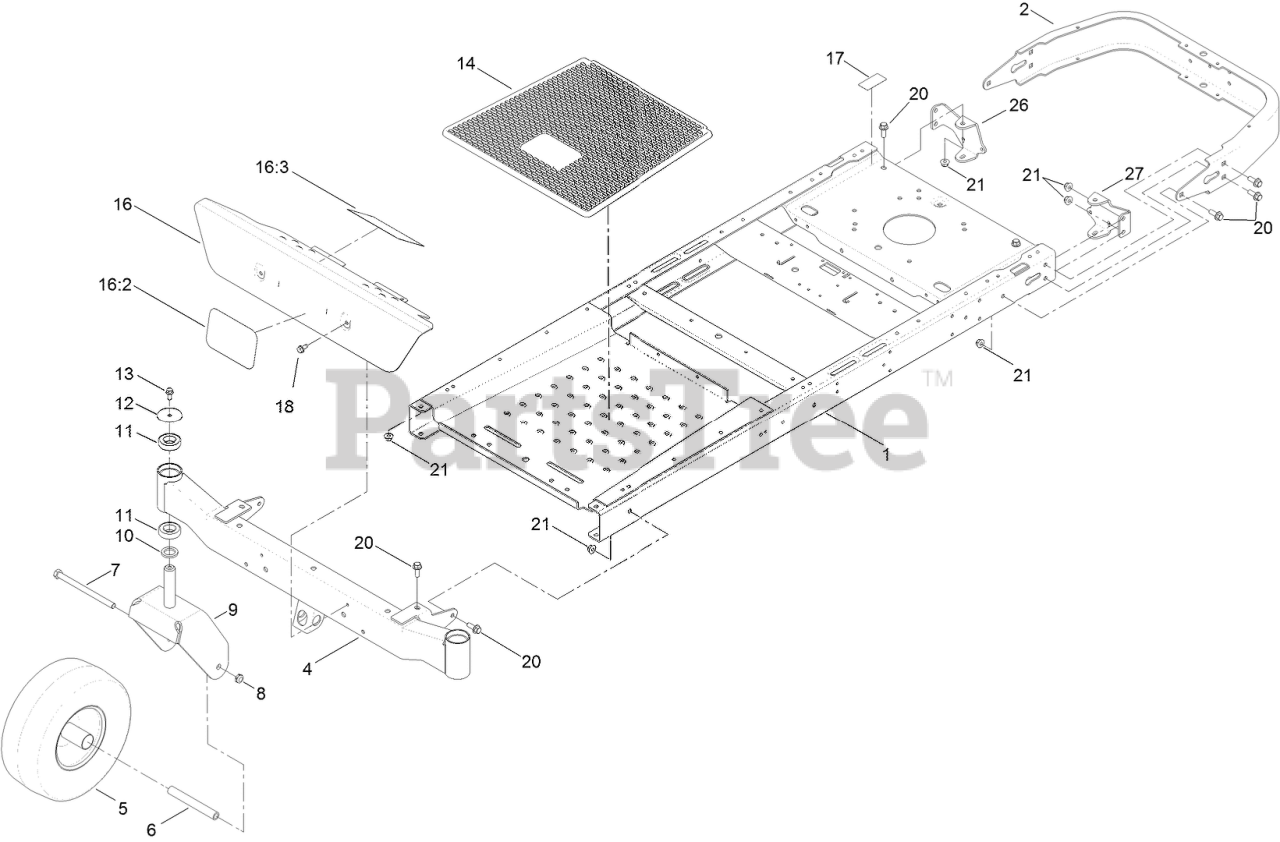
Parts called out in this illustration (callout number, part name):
2	BUMPER-REAR (WIDE)
4	AXLE-FRONT, WIDE
5	13 INCH WHEEL AND TIRE ASM
6	SPANNER
7	SCREW-HH
8	NUT-LOCK, NI
9	FORK-CASTER
10	WASHER-THRUST
11	BEARING-BALL
12	WASHER
13	SCREW-HHF
14	MAT-FLOOR
16	FOOTREST ASM
16:2	DECAL
16:3	DECAL-DANGER
17	DECAL-BYPASS
18	SCREW-HWHTF
20	SCREW-HHF
21	NUT-HF, NI
26	MOUNT-HYDRO, REAR (RH)
27	MOUNT-HYDRO, REAR (LH)
